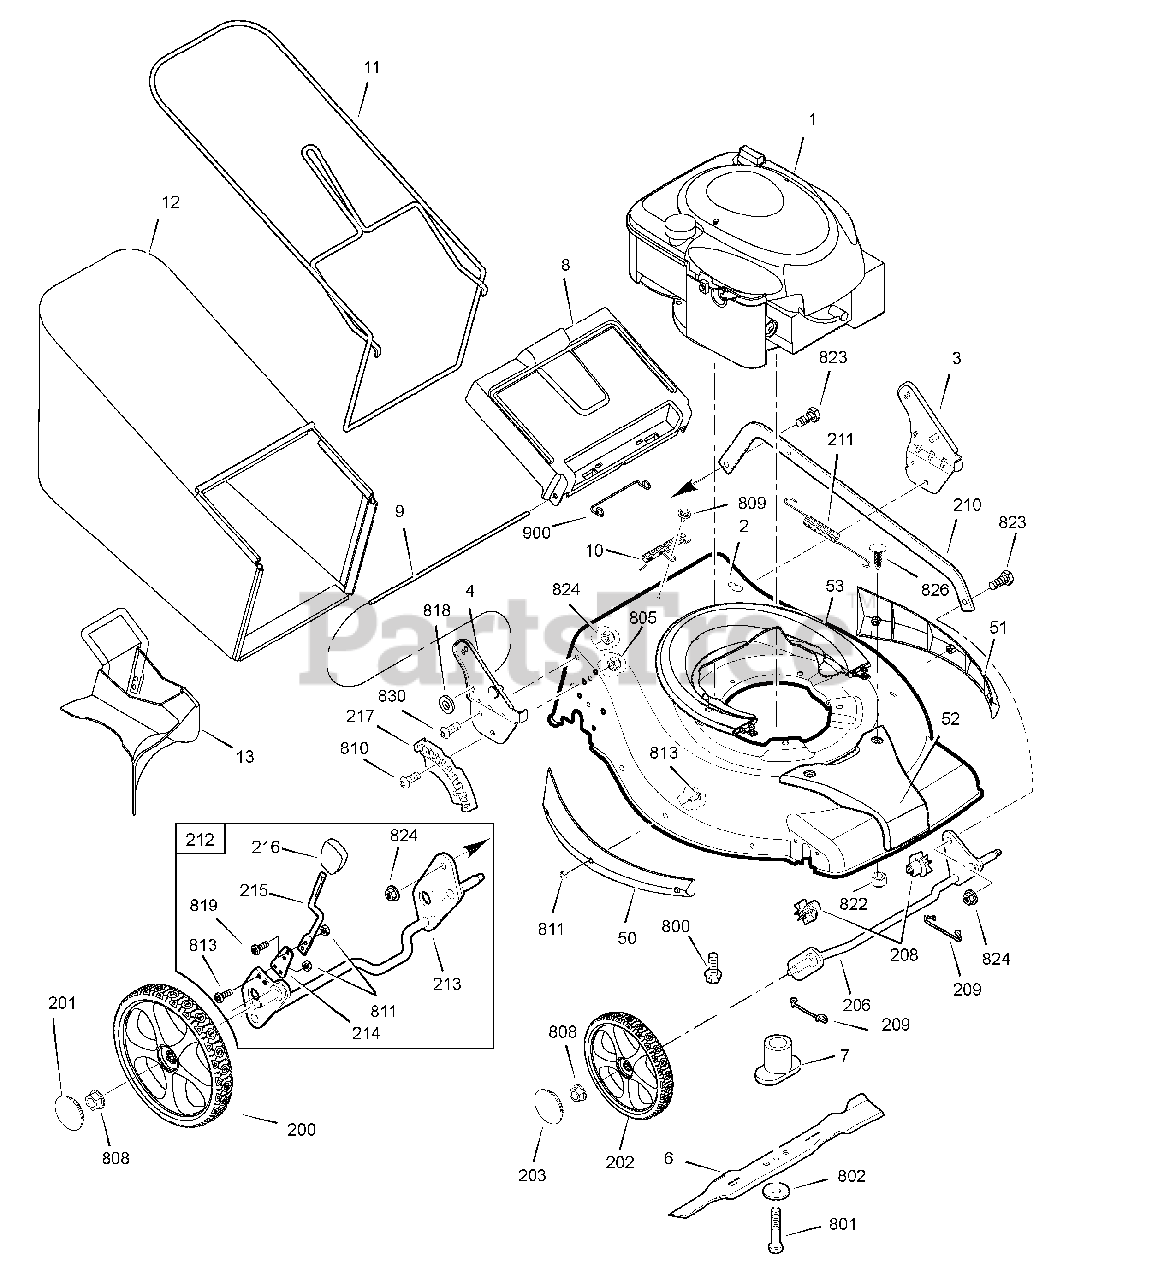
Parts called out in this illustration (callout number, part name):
1	* ENGINE, B&S 700 Series DOV, EU
2	MOWER HOUSING
3	BRACKET ASSEMBLY, Left Handle
4	BRACKET ASSEMBLY, Right Handle
6	BLADE, 19"
7	BLADE ADAPTER ASSEMBLY
8	DOOR, Rear
9	ROD, Rear Door
10	SPRING, Torsion Rear Door
11	FRAME ASSEMBLY
12	BAG ASSEMBLY
13	MULCH PLUG
50	SIDE GUARD, Right
51	SIDE GUARD, Left
52	HOUSING COVER, Front
53	HOUSING COVER, Rear
200	WHEEL, Rear
201	HUBCAP, Rear
202	WHEEL ASSEMBLY, Front, 200MM 5 Spoke Tread II SI
203	HUBCAP, Front
206	CROSSBAR ASSEMBLY, Front
208	BUSHING, Front Crossbar
209	SPRING, Clip Crossbar
210	LINK, Single Lever
211	SPRING, Extension
212	CROSSBAR ASSEMBLY, Rear (Not Available)
213	REAR CROSSBAR
214	SPRING, Adjuster
215	LEVER, Height Adjustment
216	KNOB, Adjuster
217	BRACKET, Height Adjuster
800	SCREW, Hex Head, 3/8-16 x 1
801	BOLT, Blade, 3/8-24 x 2
802	WASHER, Belleville
805	NUT, Nylock, M8 x 1-1/4
808	NUT, Flange, 3/8-16
809	SCREW, Self Tap, #10-16 x 1/2
810	BOLT, Hex Key Head
811	NUT, Nylock
813	SCREW, Torx Head, M5 x .8 x 14mm
818	NUT, Speed
819	SCREW, Torx Head, M5 x .8 x 12.5mm
822	NUT, Hex, 1/4-20
823	BOLT, Shoulder, 5/16-18 x 1
824	Nut, Flange, 5/16-18
826	SCREW, 1/4-20 x 7/8
830	SCREW , 5/16-18 x 3/4
900	SPRING CLIP, Rear Door
1000	DECAL KIT
